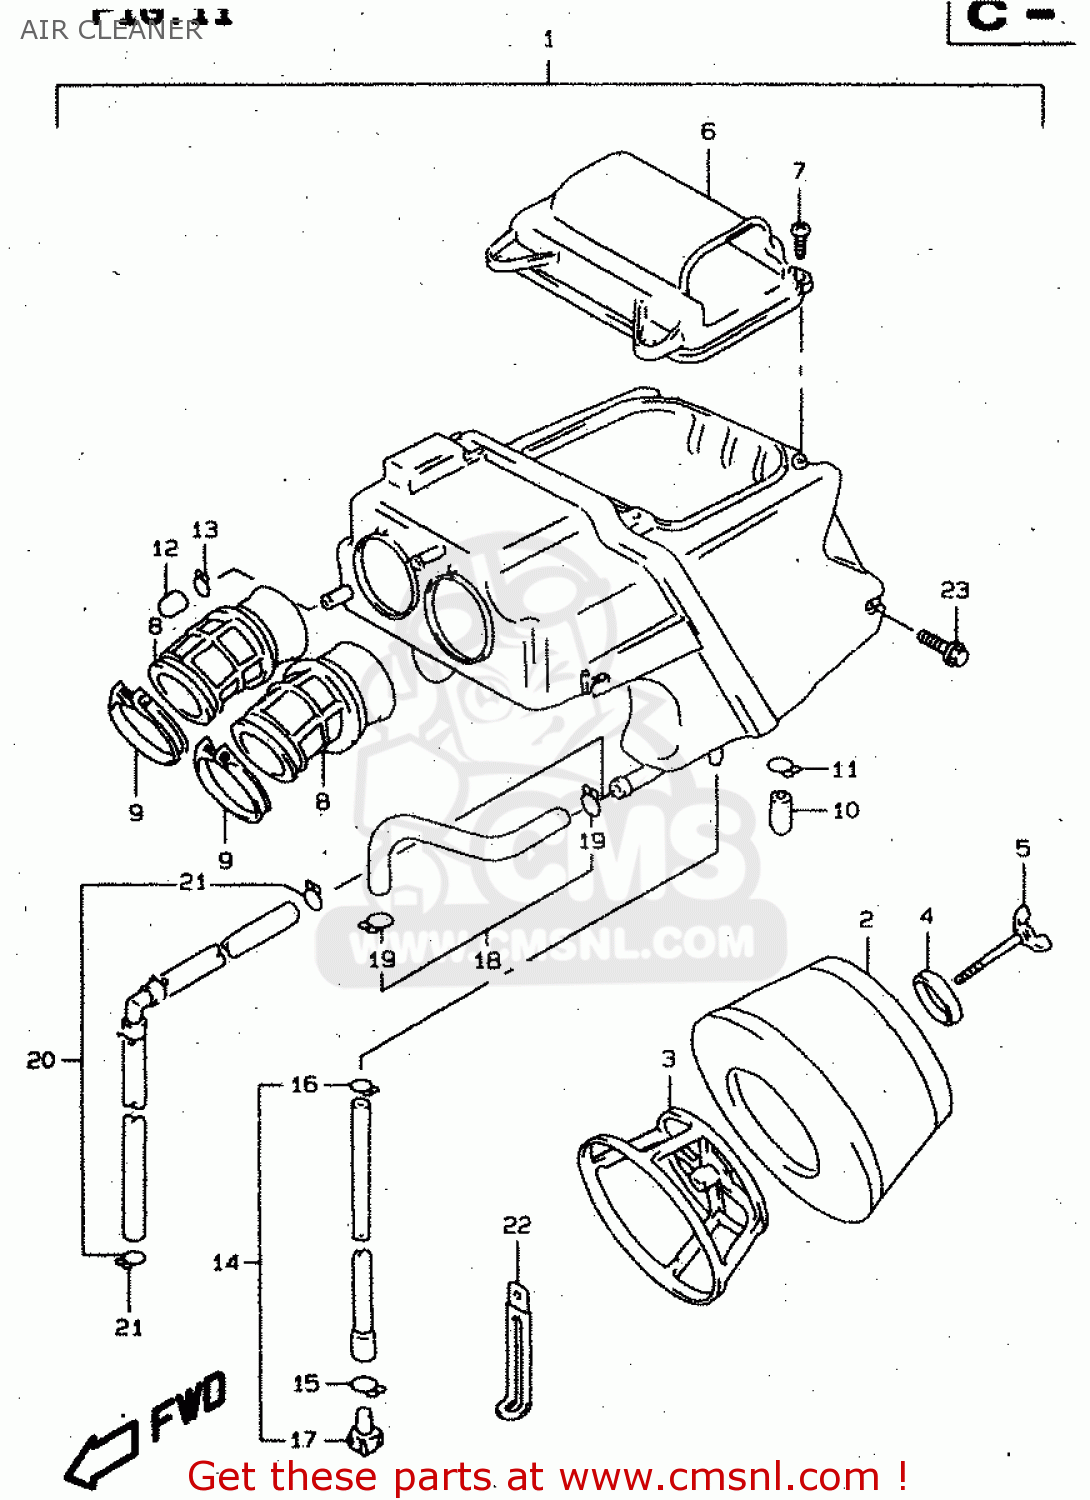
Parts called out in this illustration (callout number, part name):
1	CLEANER ASSY,A
2	FILTER,AIR CLEANER
3	HOLDER
4	WASHER,AIR CLEANER
5	BOLT L:40
6	CAP,AIR CLEANER
7	SCREW
8	TUBE,OUTLET
9	CLAMP
10	PLUG
11	CLIP
12	PLUG
13	CLIP
14	TUBE,DRAIN
15	CLIP
16	CLIP
17	STOPPER,DRAIN
18	TUBE,BREATHER
19	CLIP
20	TUBE,BREATHER
21	CLIP
22	CLAMP(L:65)
23	BOLT
